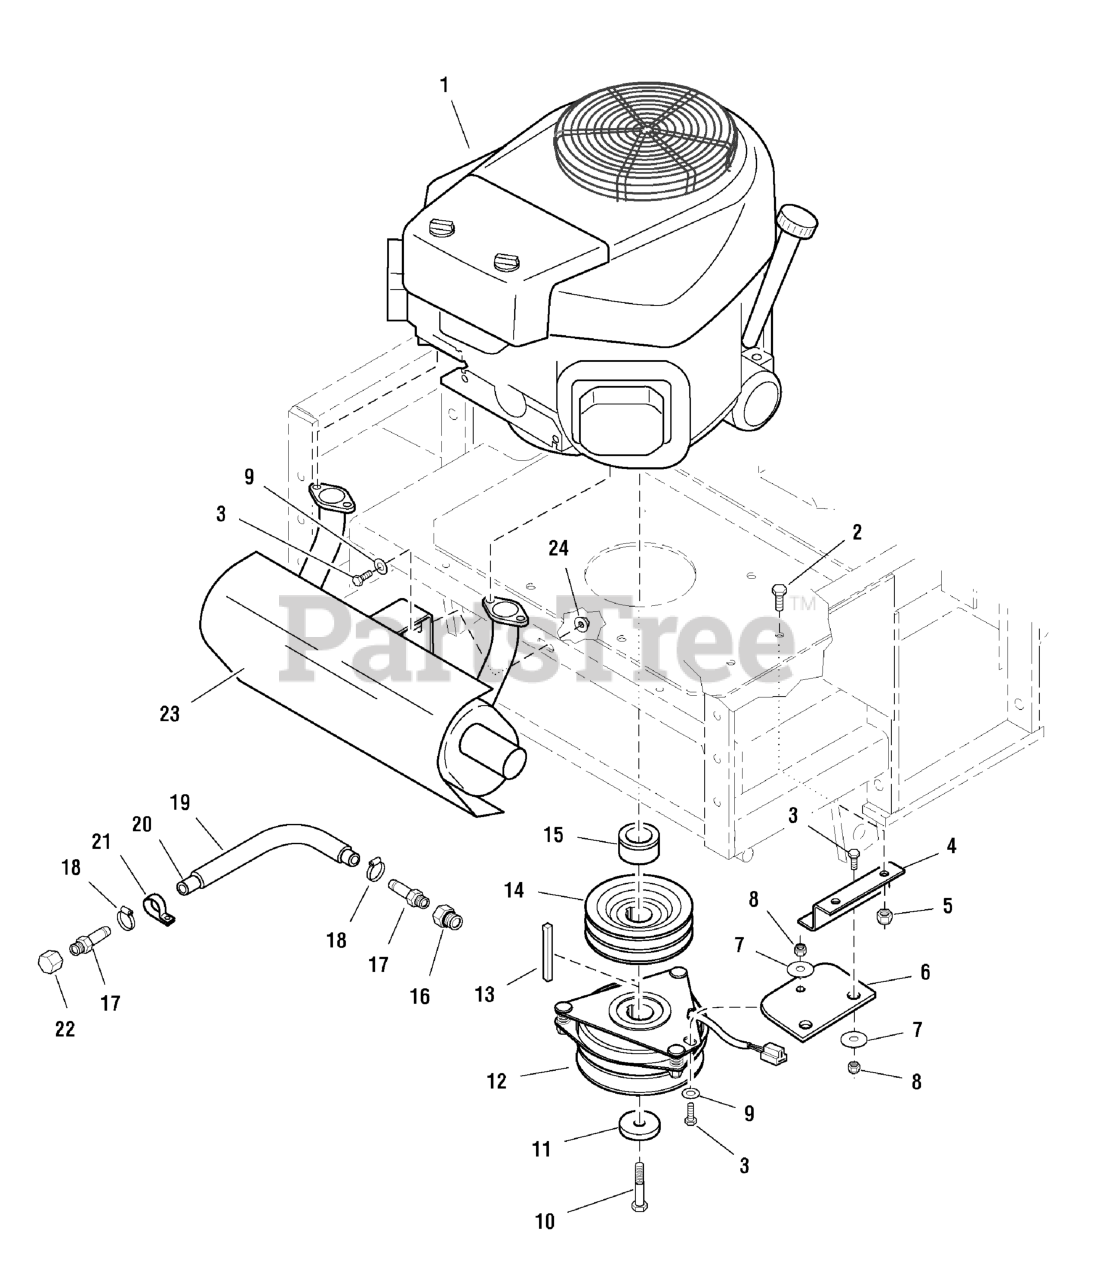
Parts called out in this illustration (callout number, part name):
1	OIL FILTER (49065-2078)
1	FUEL FILTER
2	BOLT, 3/8-16 X 1" GD5 CZ
3	BOLT, 5/16-18 X 3/4 GD5
4	ANCHOR, CLUTCH - BLK
5	NUT, 3/8-16 HEX NYLON LOCK
6	CLUTCH ANCHOR PAD
7	WASHER, 3/8" Fender
8	NUT, 5/16-18 Hex Nylon Lock
9	WASHER, 5/16" SAE
10	CRANKSHAFT BOLT, 7/16 x 2-1/4
11	SPACER, .45 x 1.88 x .38
12	ELECTRIC CLUTCH
13	KEY, 1/4 SQ. X 3
14	CRANKSHAFT PULLEY
15	SPACER, 1.13 x 1.75 x 1.03
16	ADAPTER, Oil Drain
17	FITTING, 3/8NPT-1/2" Hose, Straight
18	CLAMP, #6 Hose
19	WIRE LOOM, 12"
20	HOSE, 13"
21	CLAMP, Vinyl
22	CAP, 3/8 NPT
24	NUT, 5/16-18 HEX SERRATED FLANGE (SMALL)
